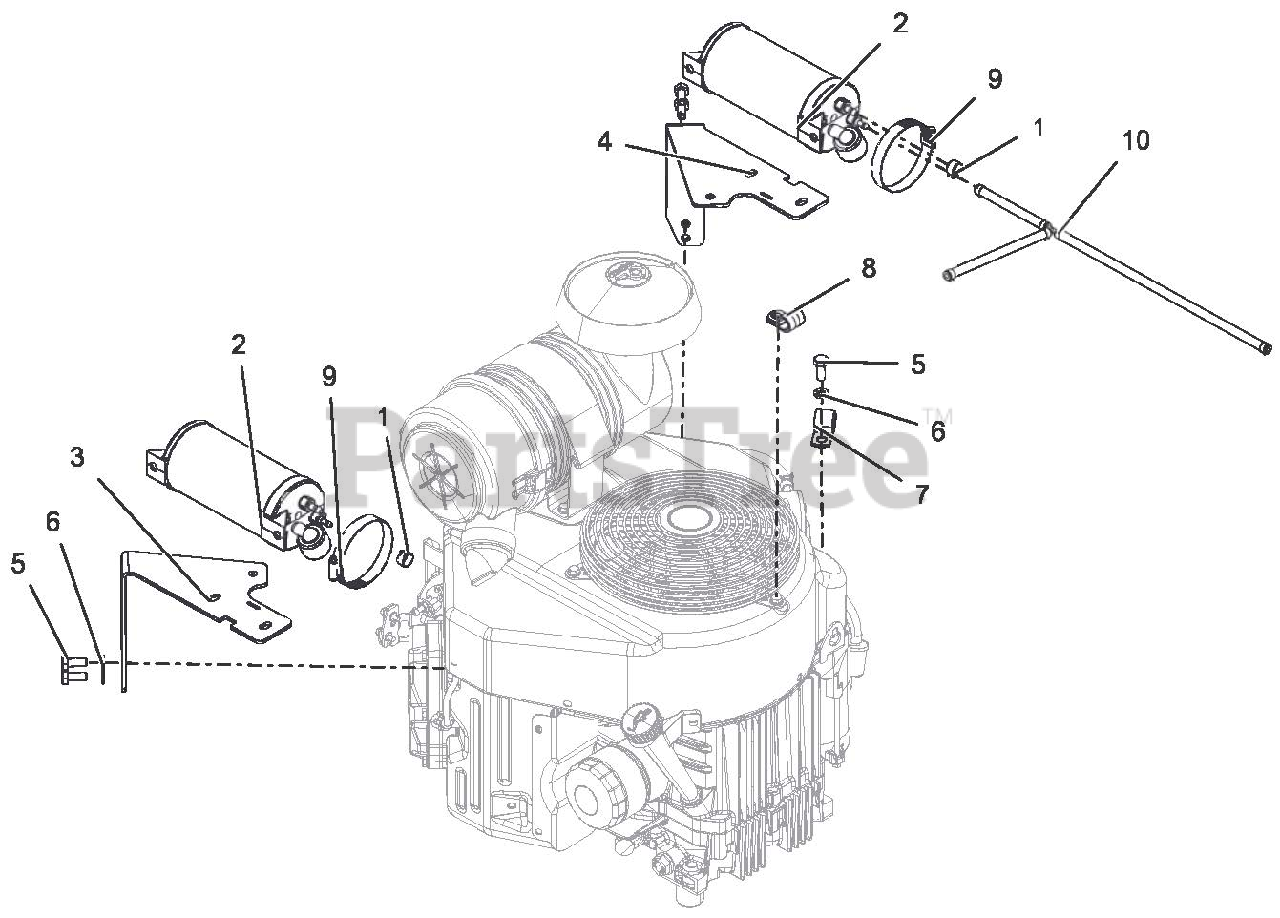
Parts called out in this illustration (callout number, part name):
1	CLAMP, FUEL LINE
2	CANISTER, CARBON 6.3 G CAP.
3	BRKT, MOUNT PT100 RH CARB CANISTER
4	BRKT, MOUNT PT100 RH CARB CANISTER
5	@BLT-HEX M8-1.25X20 YWZC
6	WSHR-LK .31X.078 REG YWZC
7	CLAMP, CUSHIONED STEEL .75
8	CLAMP, CUSHIONED STEEL
9	CLAMP, HOSE 2.3/3.2
10	ASM, FUEL LINE, PT100
